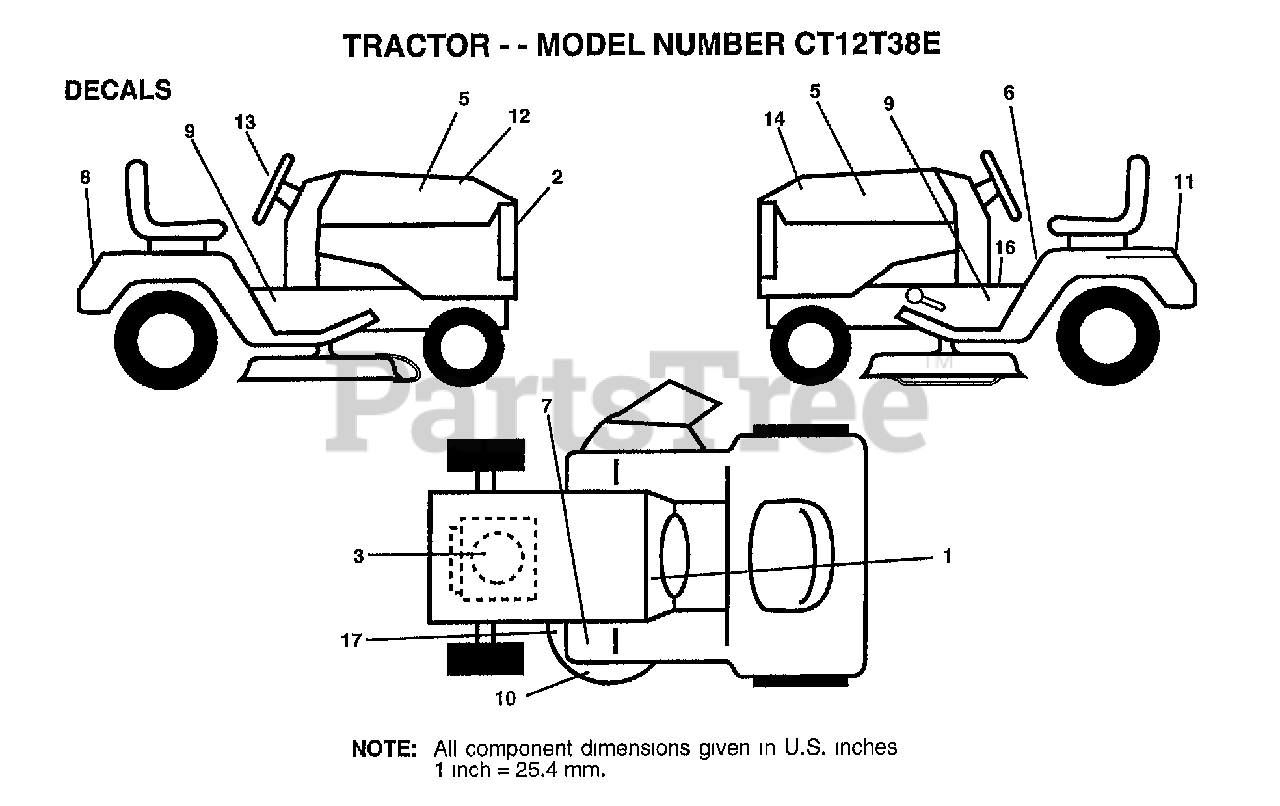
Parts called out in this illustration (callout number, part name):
1	"DECAL-OPER,GEAR D"
2	GRILL DECAL
5	"DECAL INSERT,HOOD"
6	"DECAL DANGER,FEND"
8	FENDER DECAL
9	"DECAL.CHASSIS.38"""
11	DECAL.BATRY.3-3908
12	DECAL HOOD RH RLY
13	"DECAL,STR WHL"
14	DECAL HOOD LH RLY
16	DECAL BRAK PARK
17	DECAL
